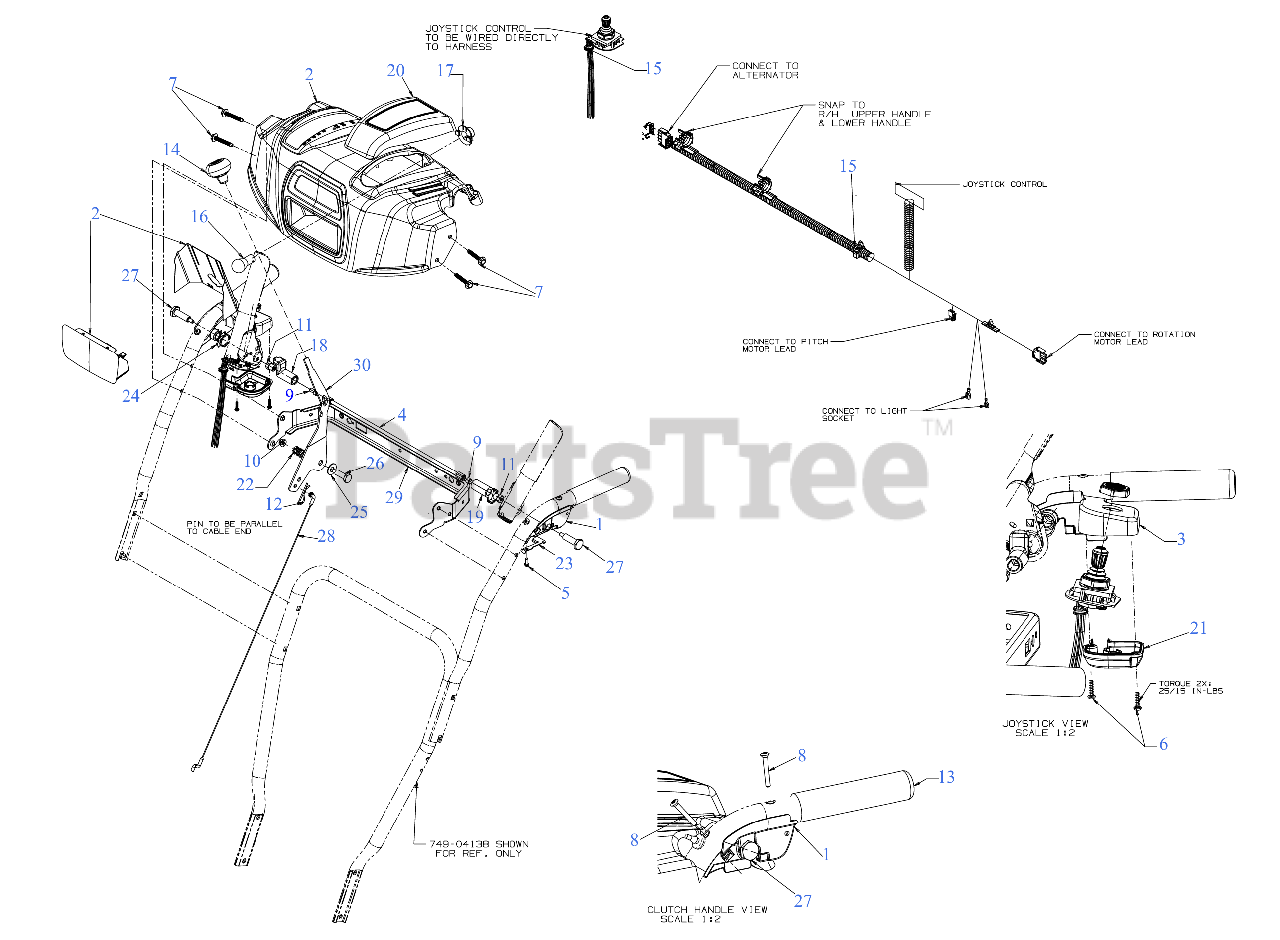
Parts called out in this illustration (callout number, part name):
1	CLUTCH LOCK HANDLE ASSEMBLY (LH)
2	HANDLE PANEL ASSEMBLY
3	CLUTCH HANDLE ASSEMBLY (RH)
4	PIVOT ROD
5	SCREW #8-16 x .50
6	SCREW .159 x .610
7	SCREW 1/4-20 x 1.625
8	SCREW #10-24 x 1.375
9	SCREW 1/4-20 x .50
10	FLANGE LOCK NUT
11	HEX NUT W/PATCH
12	INTERNAL COTTER PIN
14	SHIFT KNOB
15	4-WAY ELEC CHUTE HARNESS
16	LAMP-12 VOLT
17	HEADLIGHT SOCKET
18	LOCK PLATE
19	CLUTCH LOCK CAM
20	HANDLE COVER PANEL
21	JOYSTICK HOUSING COVER
22	COMPRESSION SPRING
23	CLUTCH SPRING
24	TORSION SPRING
25	FLAT WASHER .40X.88X.060
26	SHOULDER SCREW
27	SHOULDER SCREW .437 x 1.345 1/4-20
28	SPEED SELECTOR CABLE (PLASTIC)
29	HANDLE SUPPORT BRACKET (POWDER BLACK)
